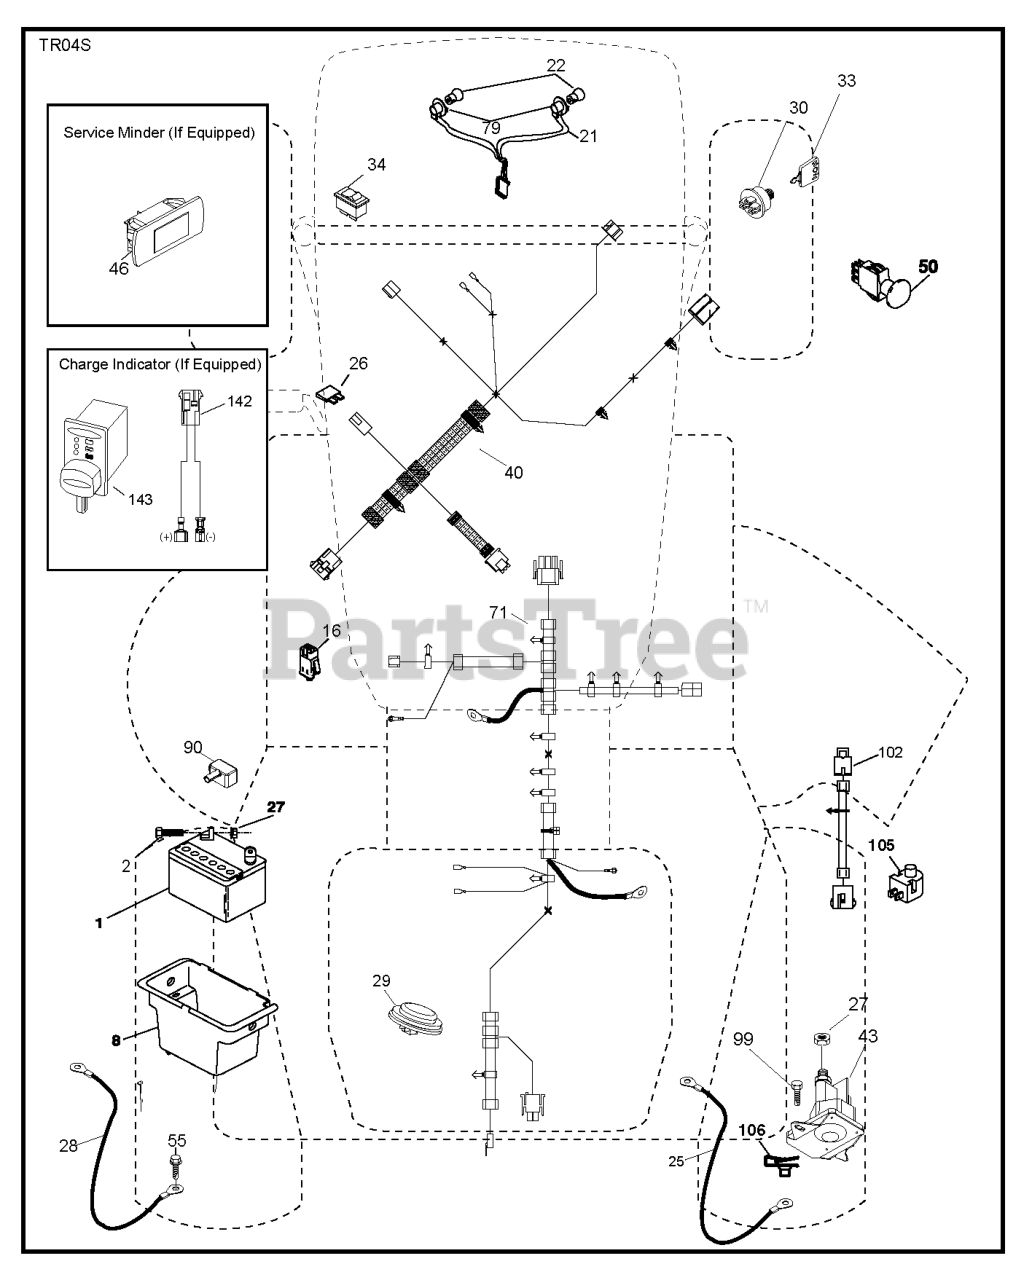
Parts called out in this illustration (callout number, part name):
1	REPL BY 532 12 38-99
2	BOLT.HEX.1/4.X.3/4.DICHROMATE
8	BOX.BATTERY.MNT.REAR.L
16	SWITCH INTERLOOK PUSH-IN
21	HARNESS.LIGHT W/4152J BULBS
22	LIGHTBULB
25	CABLE.BATT.RED.8GA.17
26	FUSE 20AMP
27	Hardware
28	CABLE.GROUND.REAR.BATTERY.8G
29	SWITCH.SEAT.DELTA.OPC.
30	SWITCH.IGN.DELTA.W.LGH.ROS
33	KEY.CHAIN.BLISTER.PACK.GEN.INT
34	SWITCH LT
40	HARNESS.TEX.DASH.ELEC.REAR BAT
43	Solenoids
46	GUAGE.SRVCMNDR.HRMTR.
50	SWITCH.PTO.8TERMINAL.STD.BLK
55	SCREW 5/16"
71	HARNESS.CHASSIS.RRBATT.RDYSTRT
79	BULB HOLDER ASM.
90	COVER.TERMINAL.BATTERY
99	SCREW HEXWSHR 1/4-20X3/4
102	HARNESS PIGTAIL PCH TEX ROS
105	REVERSE SWITCH
106	1/4-20 U NUT
